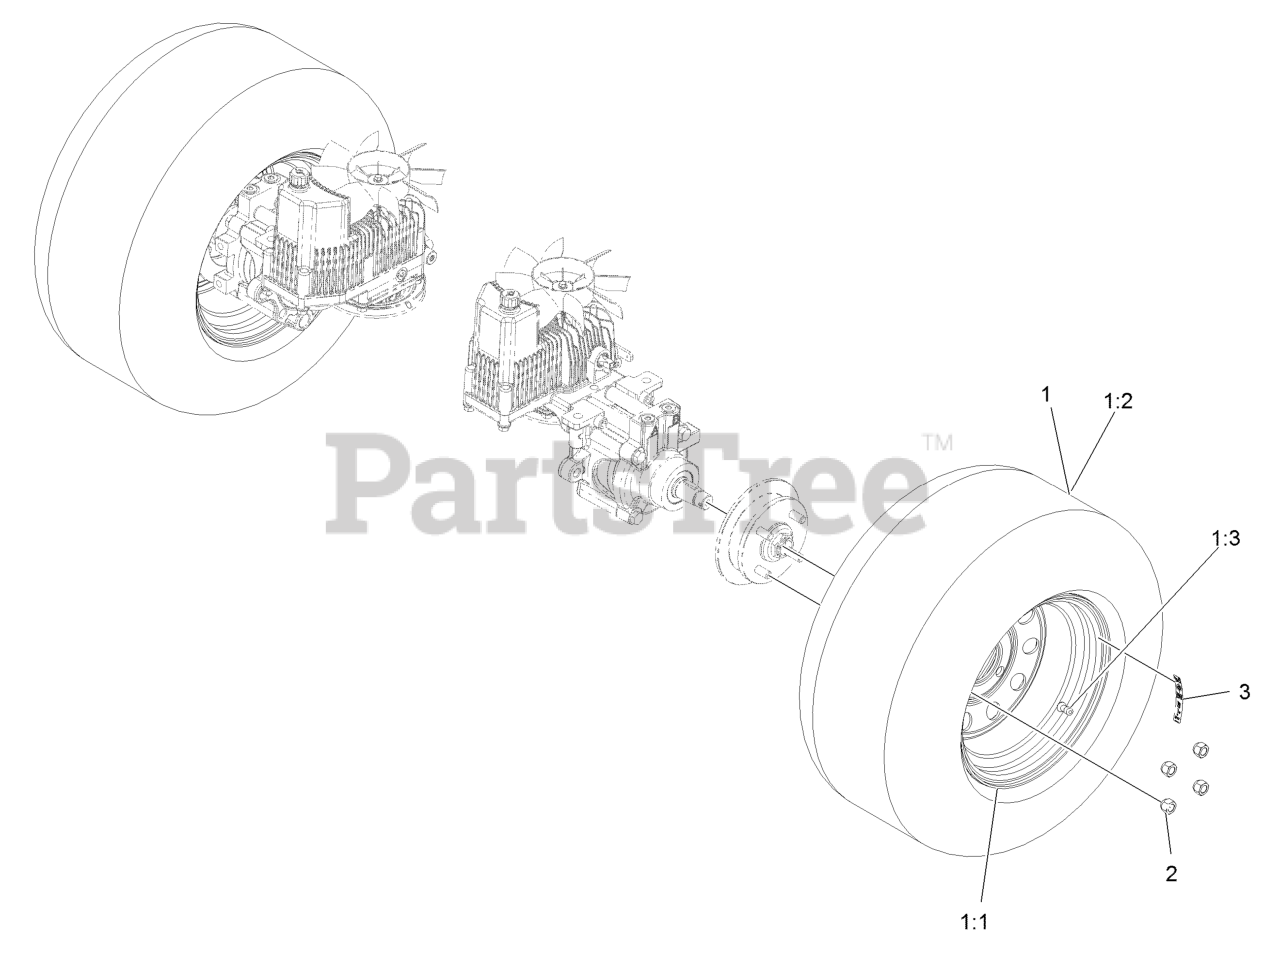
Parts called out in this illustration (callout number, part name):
1	WHEEL AND TIRE ASM
1:3	Stem-Valve
2	NUT-LUG
3	DECAL-TORQUE, WHEEL HUB LUG
